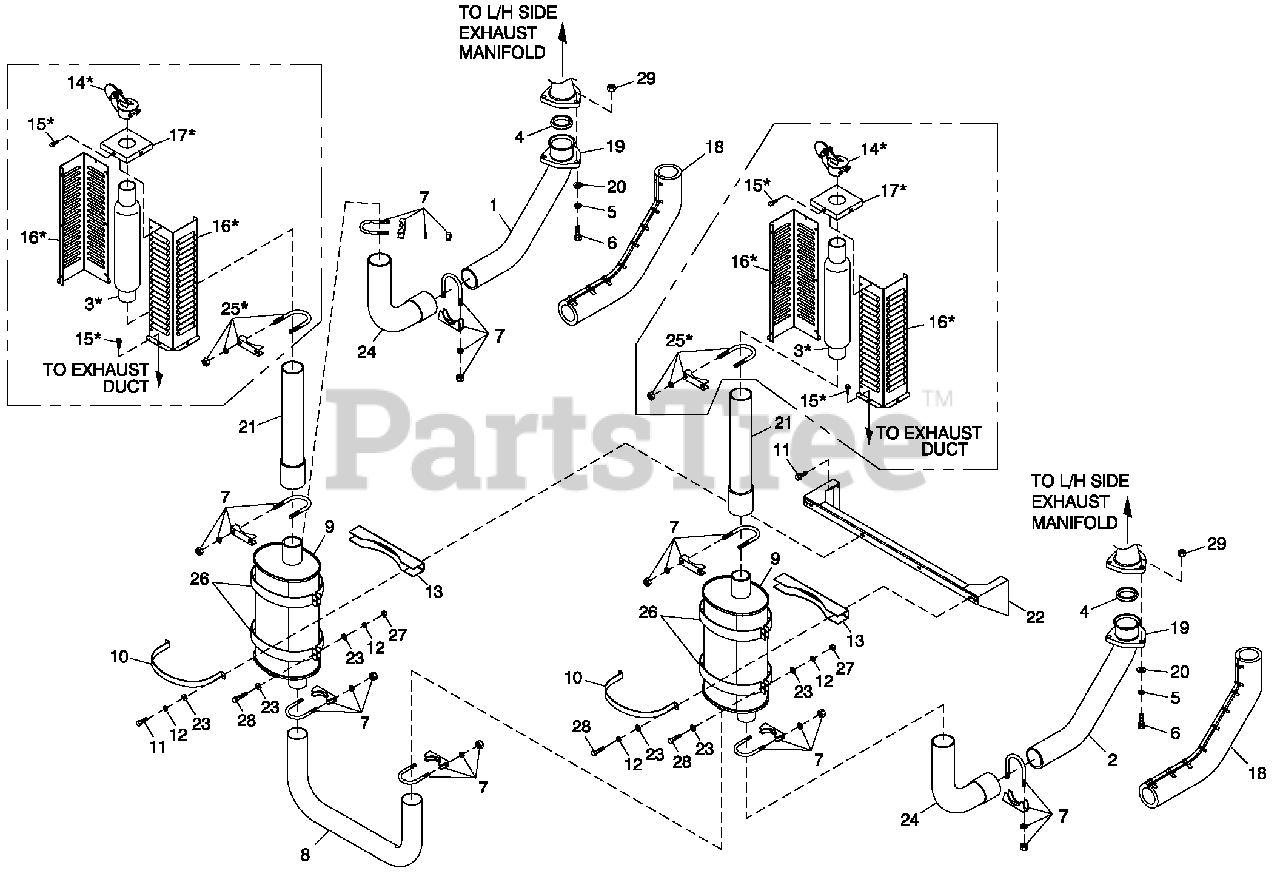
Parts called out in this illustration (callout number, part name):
1	PIPE EXH MAN R/H 6.8L G/B CPL (6.8L C5)
2	PIPE EXH MAN L/H 6.8L G/B CPL (6.8L C5)
3	GLASS PACK 23.5" LG 2.5" IN/OUT
4	RING GASKET 2.5 DIA
5	WASHER LOCK M10 SS
6	SCREW HHC M10-1.5 X 50 SS FTH
7	BOLT U 3/8-16 X 2.62
8	PIPE EXHAUST CROSSOVER
9	MFLR 7" X 9" X 25" (2) 2.5" IN/2.5" OUT
10	MUFFLER STRAP
11	SCREW THF M6-1 X 16 N WA Z/JS
12	WASHER LOCK M6-1/4
13	MUFFLER BRACKET STIFFENER
14	RAIN CAP ALUM FOR 2-1/2" PIPE
15	SCREW THF M6-1 X 16 N WA Z/JS
16	HEAT SHIELD EXHAUST STACK
17	CAP HEAT SHIELD EXHAUST STACK
18	EXHAUST BLANKET 900MM LONG (6.8L C5)
19	EXHAUST BLANKET 850MM LONG (5.4L C5)
20	FLANGE EXHAUST
21	WASHER FLAT 3/8 SS
22	EXHUAST OUTLET PIPE CPL
23	BRKT MUFFLER
24	WASHER FLAT 1/4-M6 ZINC
25	PIPE ELBOW EXHAUST MUFFLER
26	BOLT U 3/8-16 X 2.62
27	MUFFLER STRAP UPPER/LOWER
28	NUT HEX M6 X 1.0 G8 YEL CHR
29	SCREW HHC M6-1.0 X 35 G8.8 BLK
